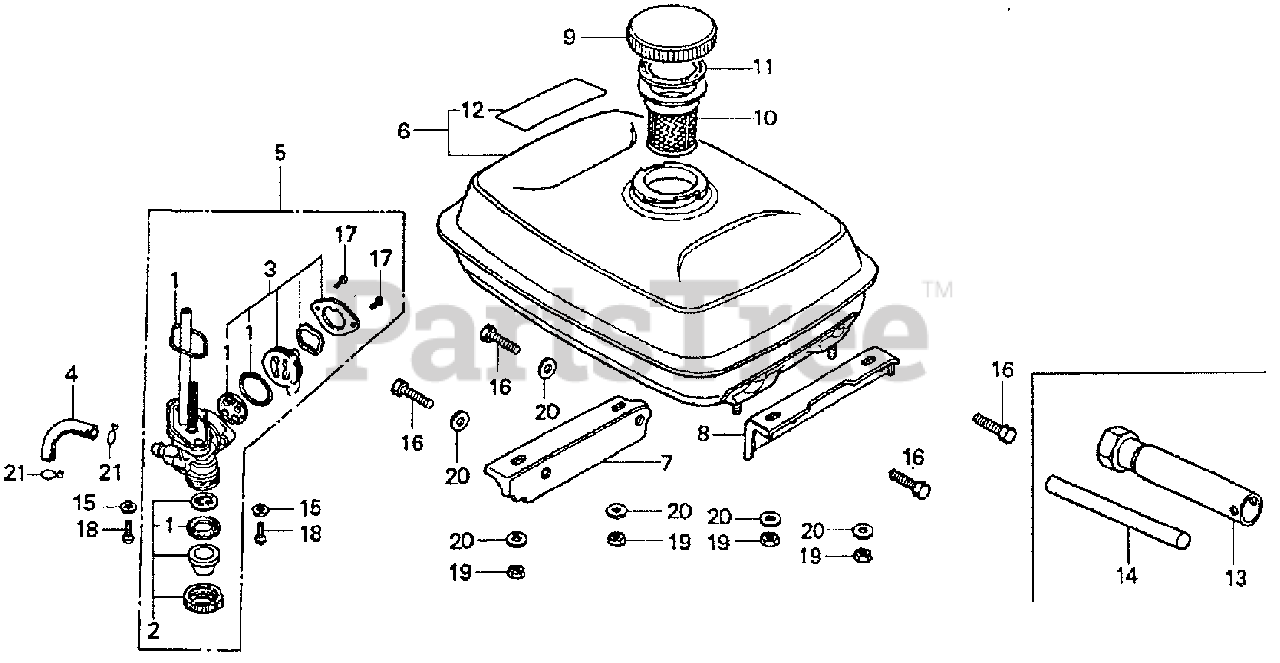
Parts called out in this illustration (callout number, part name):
1	GASKET SET, VALVE
2	CUP SET, STRAINER
3	LEVER SET, VALVE (NOT AVAILABLE)
4	TUBE, FUEL (NOT AVAILABLE)
5	PETCOCK ASSY.
6	TANK, FUEL *NH31* (MCKINLEY WHITE) (NOT AVAILABLE)
7	STAY A, FUEL TANK *R8* (BRIGHT RED)
8	STAY B, FUEL TANK *R8* (BRIGHT RED)
9	CAP, FUEL TANK (NOT AVAILABLE)
10	FILTER, FUEL
11	GASKET, FUEL FILTER (NOT AVAILABLE)
12	MARK A, CAUTION
13	WRENCH, SPARK PLUG (NOT AVAILABLE)
14	HANDLE, BOX WRENCH
15	GASKET, FIBER (6MM)
16	BOLT, HEX. (8X25)
17	SCREW, PAN (3X8)
18	SCREW, PAN (6X16)
19	NUT, HEX. (8MM)
20	WASHER, PLAIN (8MM)
21	CLIP, TUBE (B12)
